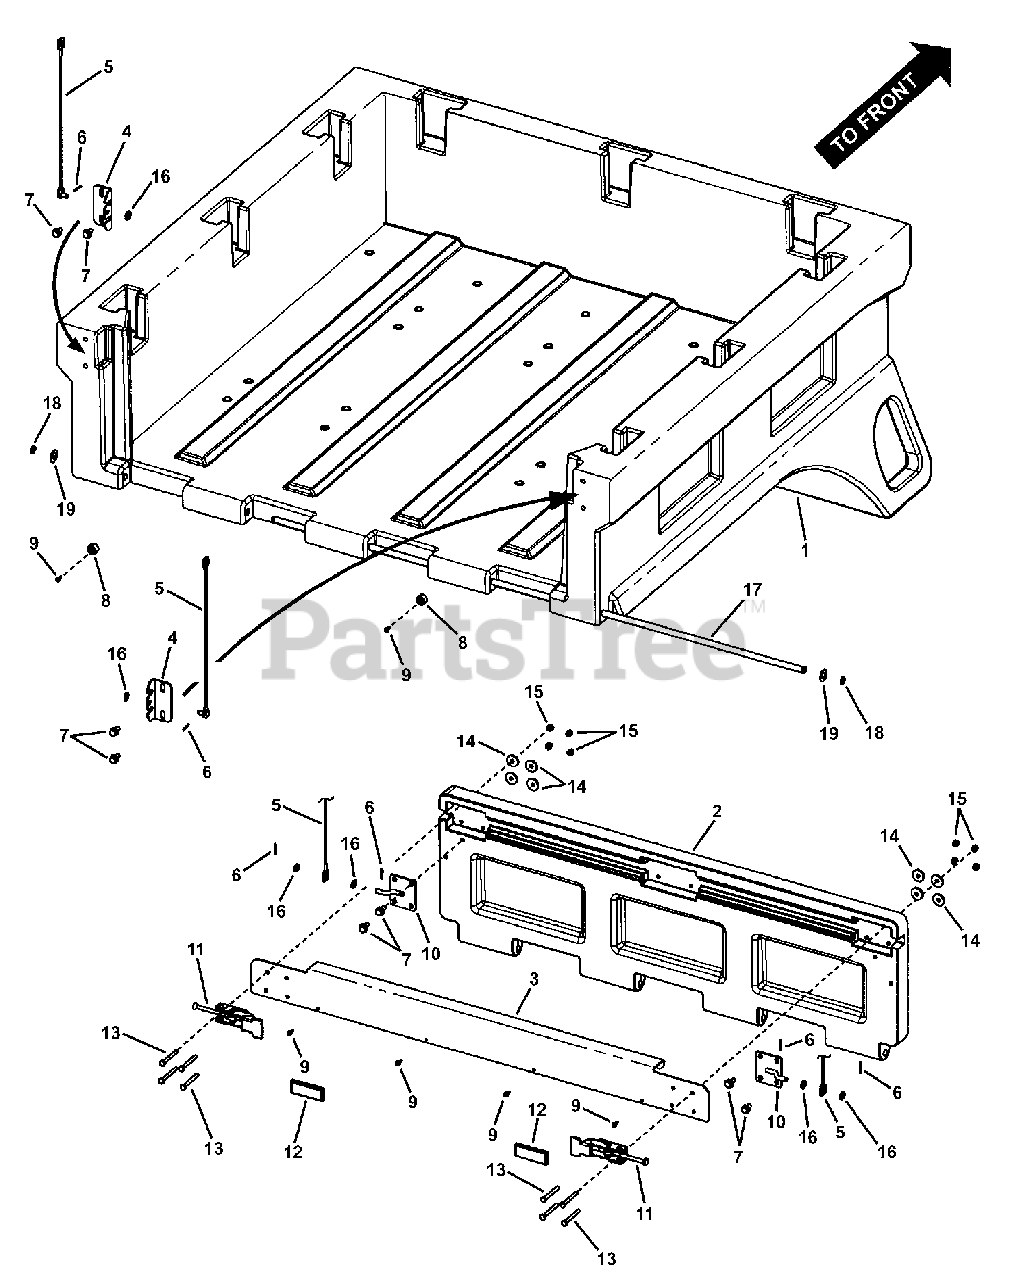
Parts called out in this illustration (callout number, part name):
1	BED, Plastic
2	TAILGATE, Plastic
3	COVER, Tailgate
4	BRACKET, Latch LH
5	LANYARD, Tailgate
6	COTTER PIN, 3/32 x 3/4
7	BOLT, Hex Flange Lock, 5/16-18 x 5/8
8	BUMPER, Recess Style
9	SCREW, #10 x 5/8, HiLo Nail Point
10	BRACKET, Gate (weldment)
11	LATCH, Tailgate
12	REFLECTOR, Red
13	CAPSCREW, Hex Head, G1/4-20 x 2-1/4 Hex Head, GR 5
14	WASHER, .281 x 1.00 x .125 Flat
15	NUT, Hex Nyloc, 1/4-20
16	WASHER, .34 x .69 x .08 Flat
17	ROD, Tailgate
18	RETAINING RING, 1/2, Heavy Duty
19	WASHER, .5 x 1.0 x .03 Flat
